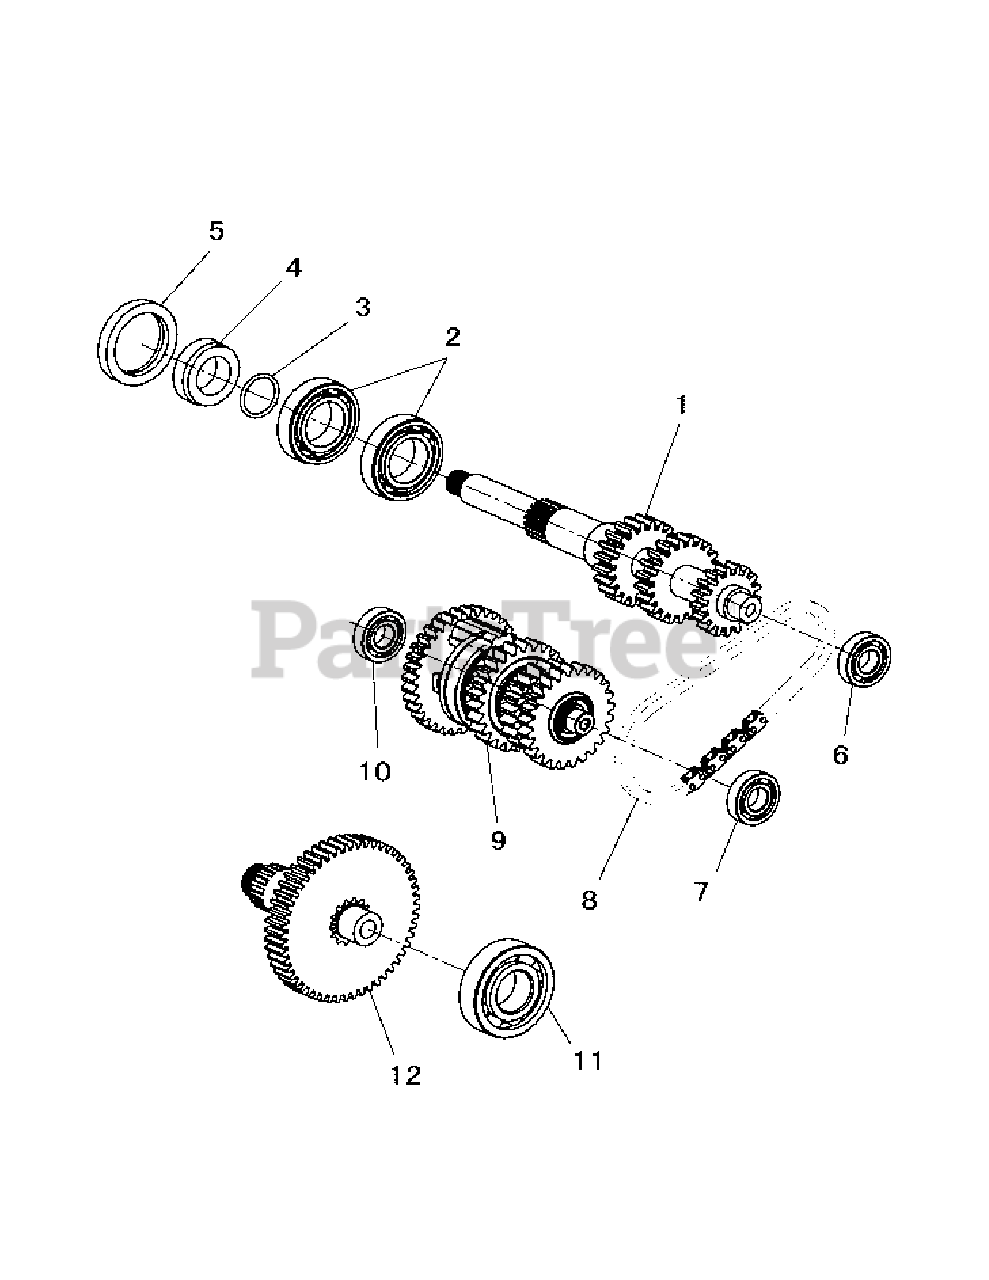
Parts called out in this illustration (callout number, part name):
3	O-Ring 26.1X2.4
4	Collar Sheath 26×42×14.7
5	Seal-Fuel 42×55×8
8	Chain-Gear Type M9-9.25-34
9	Middle Shaft-Comp
10	Bearing-6203DLA8
12	Output Shaft Asm
